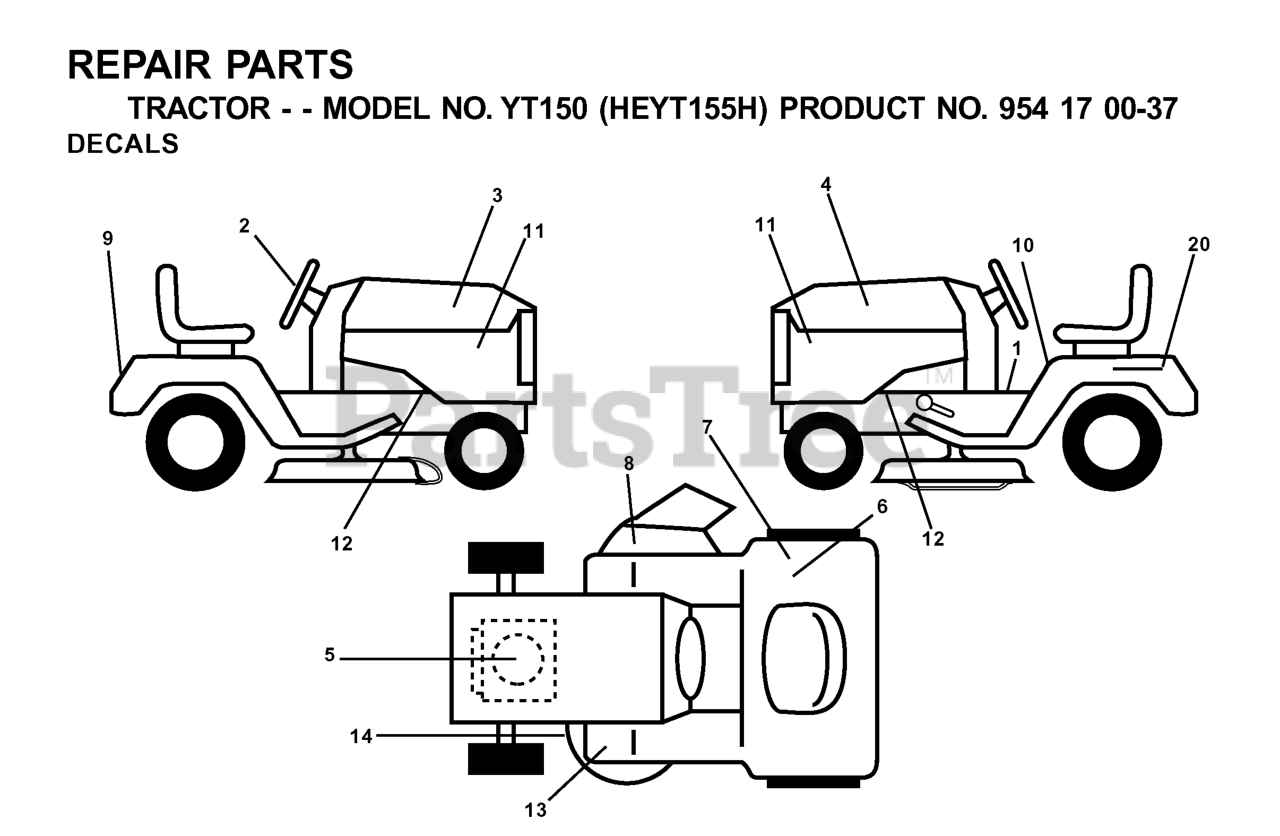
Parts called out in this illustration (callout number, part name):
1	DECAL PARK BRAKE
2	DECAL.WHEEL.STEERING.HUSQ.PERM
3	Decal Hood RH
4	Decal Hood LH
5	Decal Hp Engine
6	DECAL CERTIFICATION
7	DECAL EUROPE STANDARD CE
8	DECAL MOWER CUT/FINGER
9	DECAL FENDER HUSQ
10	DECAL READ OWNER'S MAN SYMS
11	DECAL PNL SIDE
13	DECAL
14	DECAL V BELT SCHEMATIC
20	DECAL BTRY SYMBOLS
